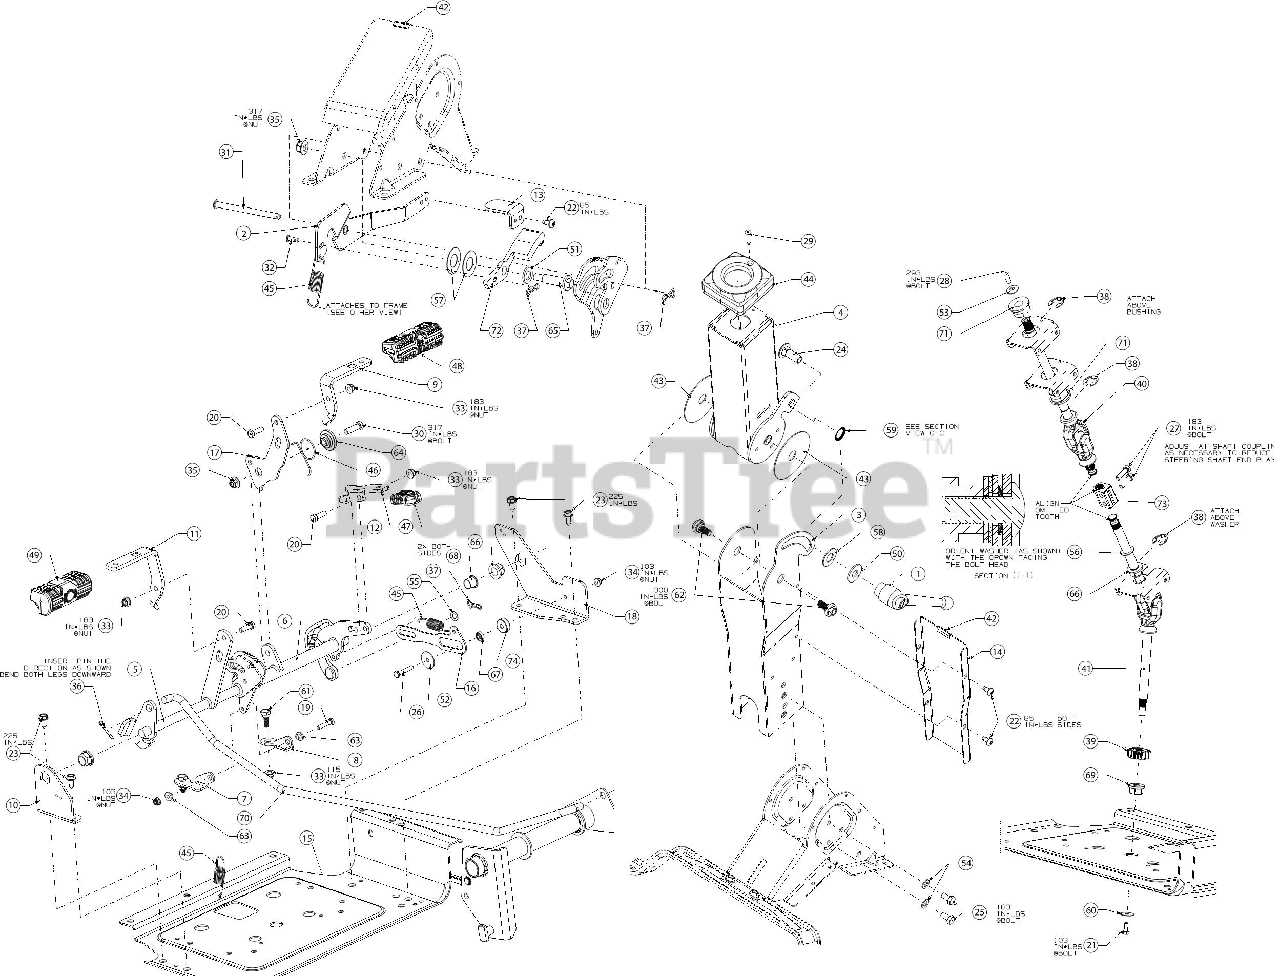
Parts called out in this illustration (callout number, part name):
1	LEVER - ADJ STEERING
2	CRUISE/BRAKE ARM
3	LOWER COLUMN ASSEMBLY
4	UPPER PIVOT COLUMN ASSEMBLY
5	BRAKE SHAFT ASSEMBLY
6	DRIVE PEDAL SHAFT ASSEMBLY
7	PEDAL SHAFT BRACKET (LH)
8	PEDAL SHAFT BRACKET (RH)
9	FORWARD DRIVE PEDAL
10	BEARING SUPPORT BRACKET
12	REVERSE DRIVE PEDAL
13	TILT STEERING PEDAL
14	STEERING COLUMN COVER
15	RZT FRAME
16	NEUTRAL RETURN LINK
17	FORWARD PEDAL BRACKET
18	PEDAL BEARING BRACKET (RH)
19	HEX SCREW 1/4-20 x 1.25
20	SCREW 5/16-18 x 1.0 GR5
21	SCREW 1/4-20 x .62 SPEC GR5
22	SCREW 1/4-20 x .500
23	SCREW 5/16-18 x .750
24	CARRIAGE BOLT 1/2-13 x 1.25 GR5
25	SCREW 5/16-18 x .62 GR5
26	SCREW 1/4-20 x 1.50 GR.5
27	SCREW 5/16-18 x 1.00 GR5
28	SCREW 5/16-24 x .875 GR5
29	SCREW #10-16 x 1.25
30	SCREW 3/8-16 x 1.25 GR5
31	CLEVIS PIN 5/16 x 4.135
32	CLEVIS PIN .224 x .625
33	FLANGE LOCK NUT 5/16-18
34	FLANGE LOCK NUT
36	COTTER PIN-5/32 DIA
37	BOW TIE COTTER PIN 1/4-5/16
38	E-RING
39	STEERING GEAR 14T
40	UPPER STEERING SHAFT
41	LOWER STEERING SHAFT
42	TRIM STRIP
43	COLUMN PLATE
44	STEERING COLUMN COVER
45	EXTENSION SPRING
46	TORSION SPRING
47	REVERSE PEDAL PAD
48	FORWARD PEDAL PAD
49	BRAKE PEDAL PAD
50	FLAT WASHER
51	FLAT WASHER .535 x .930 x .090
52	FLAT WASHER
53	BELL WASHER .337 X.867 x .057
54	FLAT WASHER
55	WASHER THRUST .375X.70X.030
56	FLAT WASHER
57	THRUST WASHER
58	FLAT WASHER NYLON 5/8
59	LOCK WASHER
60	FLAT WASHER
61	SHOULDER SCREW .437
62	SHOULDER SCREW .625X.165X3/8-16
63	SHOULDER SPACER
64	SHOULDER SPACER 1.50X.38X.38
65	SHOULDER SCREW .496X1.44 3/8-16
66	FLANGE BEARING
67	BALL BEARING .25 x .625 SPCL
68	NYLINER BEARING
69	FLANGE BEARING
70	FRONT BRAKE ROD
71	FLANGE BEARING
72	CRUISE LATCH
73	STEERING SHAFT COUPLING
74	SPACER .267X1.00X.36
